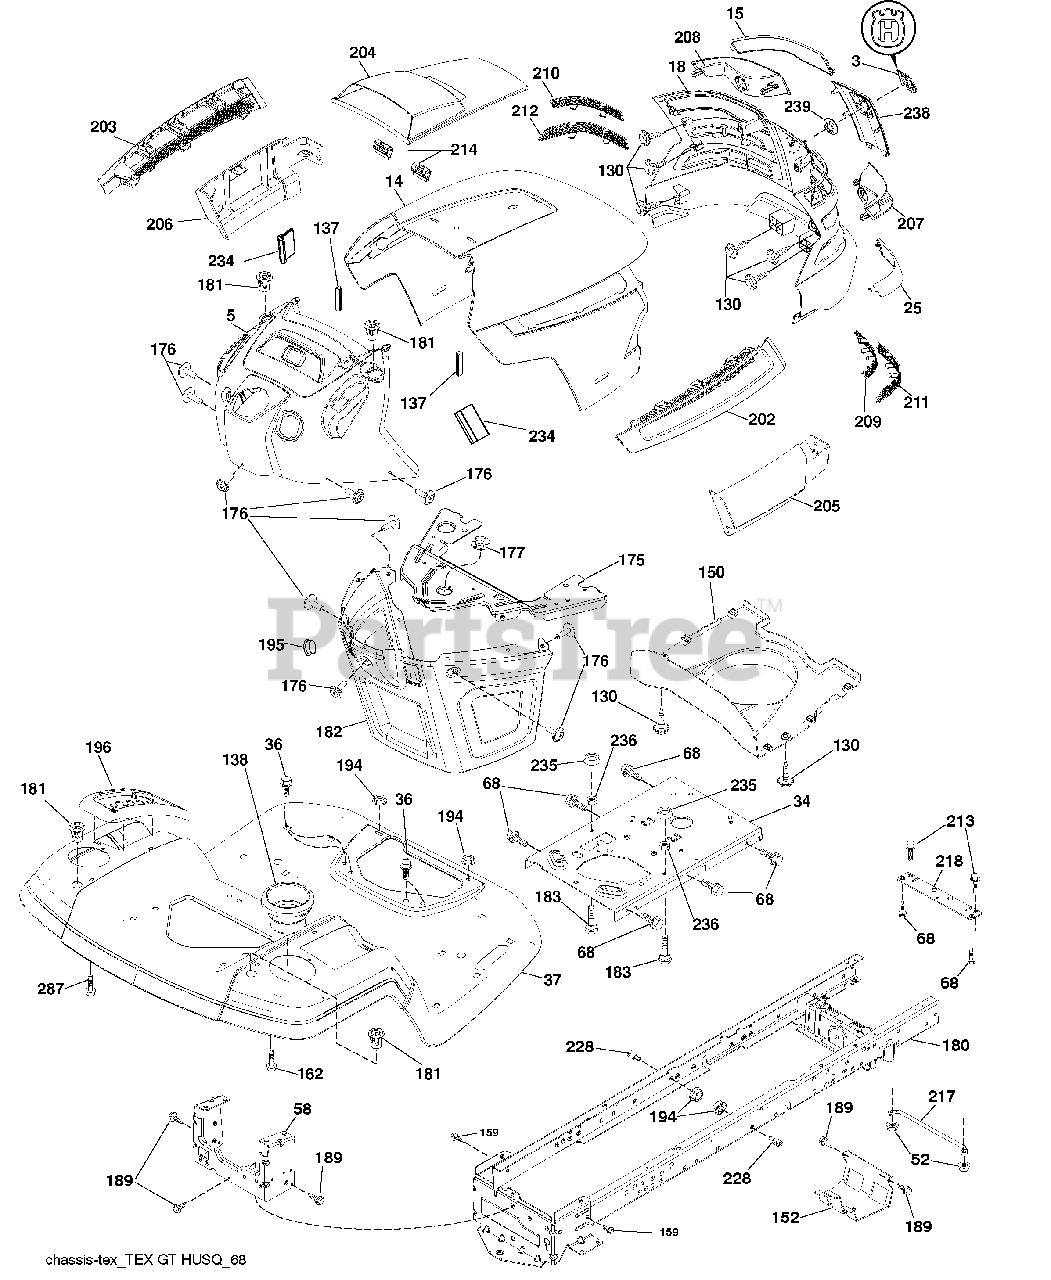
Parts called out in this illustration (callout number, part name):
3	Logo
14	Hood
18	Grille/Lens Asm.
34	Plate Engine
36	Screw 5/16-18 x 3/4
37	Fender
52	Nut Lock 5/16-18
58	Drawbar Upper 2PC Sml. Fender
68	Screw Thdrol 5/16-18 x 1/2
130	Screw #10 x 0.750
137	Bumper Dash
138	Cupholder
152	Shield Browning
159	Screw Hexwsh Thrd 3/8-16 x 3/4
175	Crossmember Plate
176	Screw 10-24 x 5/8
177	Bushing Steering
181	Bushing Mtg. Fender Crgo
182	Dash Lower
183	Bolt Fin Hex 5/16-18 unc x 1-1/4
189	Screw 5/16-18 x 3/4
194	Nut Lock Hex Flange 5/16-18
195	Plug Hole Dash Lower
196	Console Asm. Deck Lift
202	Vent Side Hood RH
203	Vent Side Hood LH
204	Vent Top Hood
205	Skirt Hood Side RH
206	Skirt Hood Side LH
209	Insert Hex Top RH
210	Insert Hex Top LH
211	Insert Hex Bottom RH
212	Insert Hex Bottom LH
213	Bolt 5/16-18 x 3/4
214	Clip Retainer Tinner
218	X-Piece Hood Stop
228	Stud Fastner
234	Bumper Hood
235	Spacer Fender
236	Nut Lock 5/16-18 unc
287	Screw 1/4-20 x 3/8
